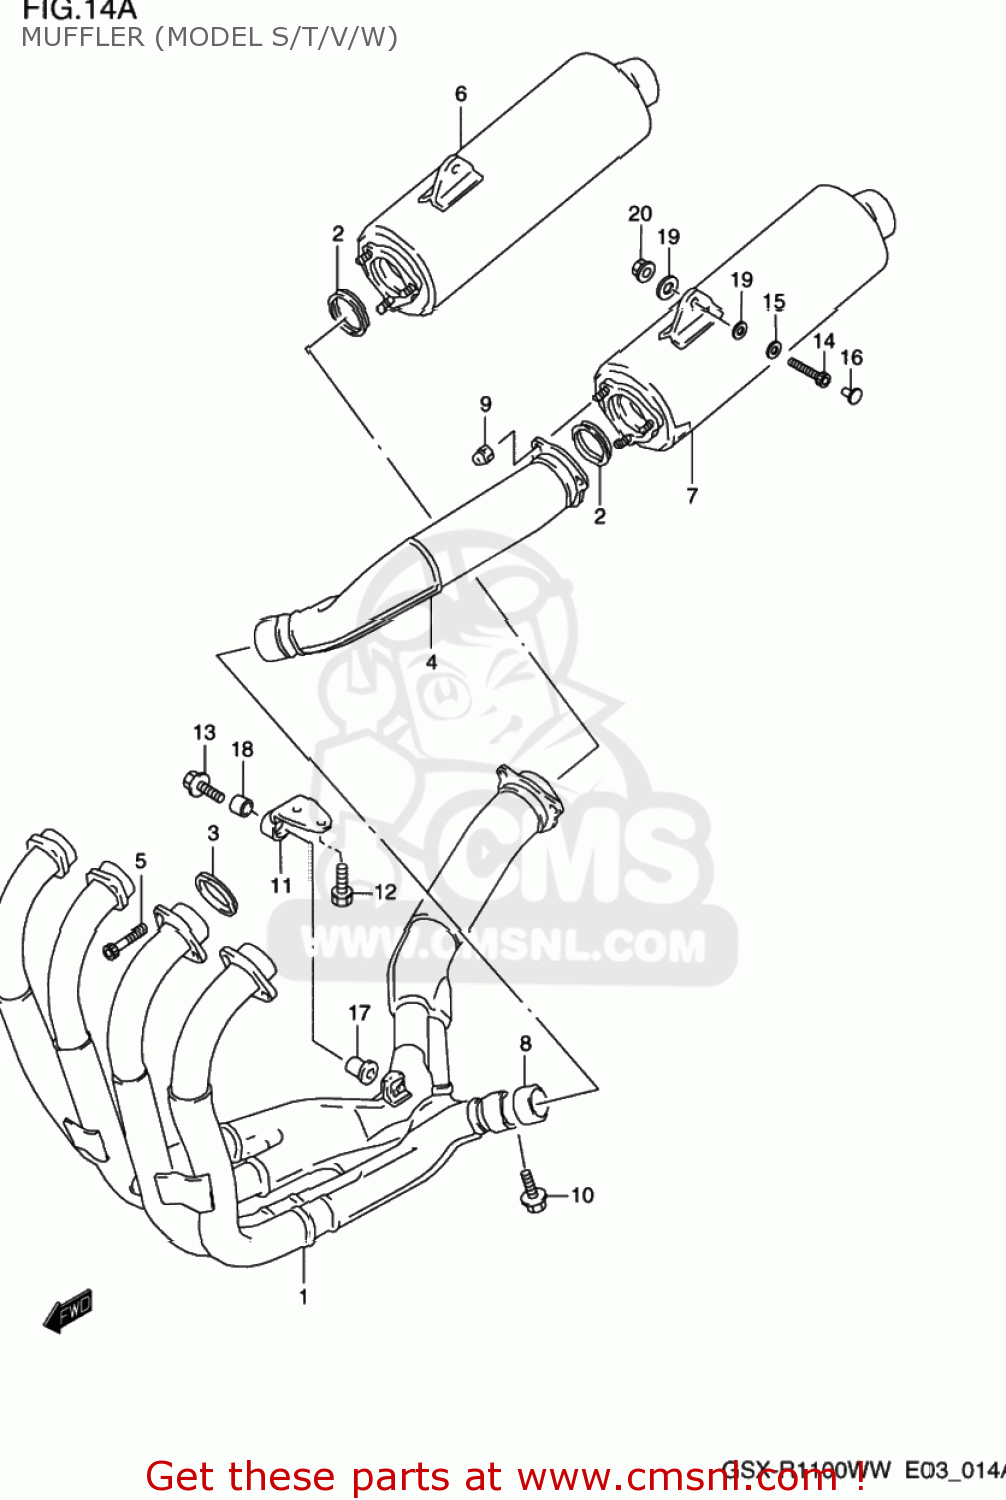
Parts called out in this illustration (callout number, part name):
1	EXHAUST
2	GASKET,MUFFLER JOINT
3	GASKET,EXHAUST PIPE
4	PIPE,JOINT,L
5	BOLT
6	BODY,MUFFLER.R
7	BODY,MUFFLER,L
8	CONNECTOR,MUFFLER
9	NUT
10	BOLT
11	BRACKET,EXHAUST SUPPORT
12	BOLT(8X20)
13	BOLT 8X40
14	BOLT
15	WASHER
16	CAP(OD:12)
17	SPACER(8.6X12X18.5)
18	CUSHION
19	WASHER (10.5X24X2.3)
20	NUT
